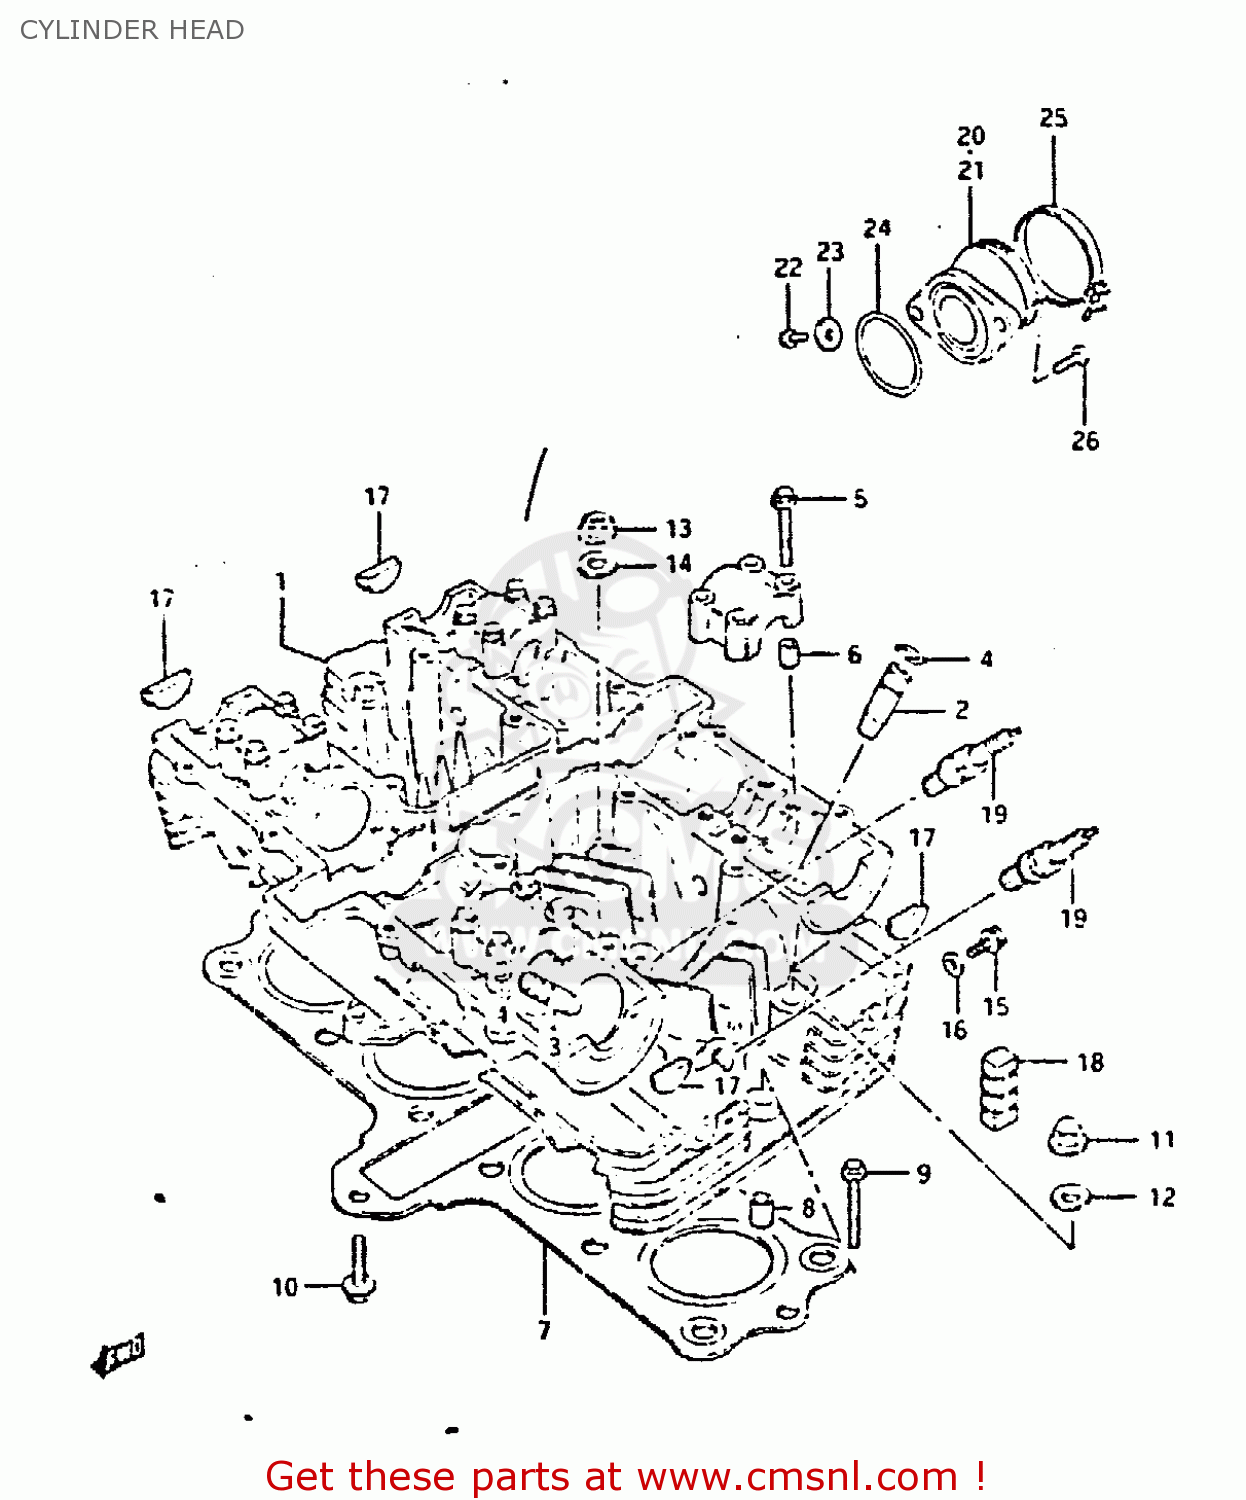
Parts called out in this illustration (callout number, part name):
1	HEAD,CYLINDER
2	GUIDE,INTAKE VALVE
3	GUIDE,EXHAUST VALVE
4	RING,SNAP
5	BOLT(6X39)
6	PIN(6.2X8X11)
7	GASKET,CYLINDER HEAD (MCA)
8	PIN
9	BOLT (6X45)
10	BOLT 6X30
11	NUT
12	GASKET (NAS)
13	NUT
14	WASHER(8.5X19X2.3)
15	BOLT 6X12
16	WASHER
17	PLUG
18	PAD,RUBBER N4
19	SPARK PLUG DR8ES-L
20	PIPE,INTAKE,R
21	PIPE,INTAKE,L
22	SCREW (5X10)
23	WASHER
24	O RING(D:2.4,ID:37.7)
25	CLAMP
26	SCREW
